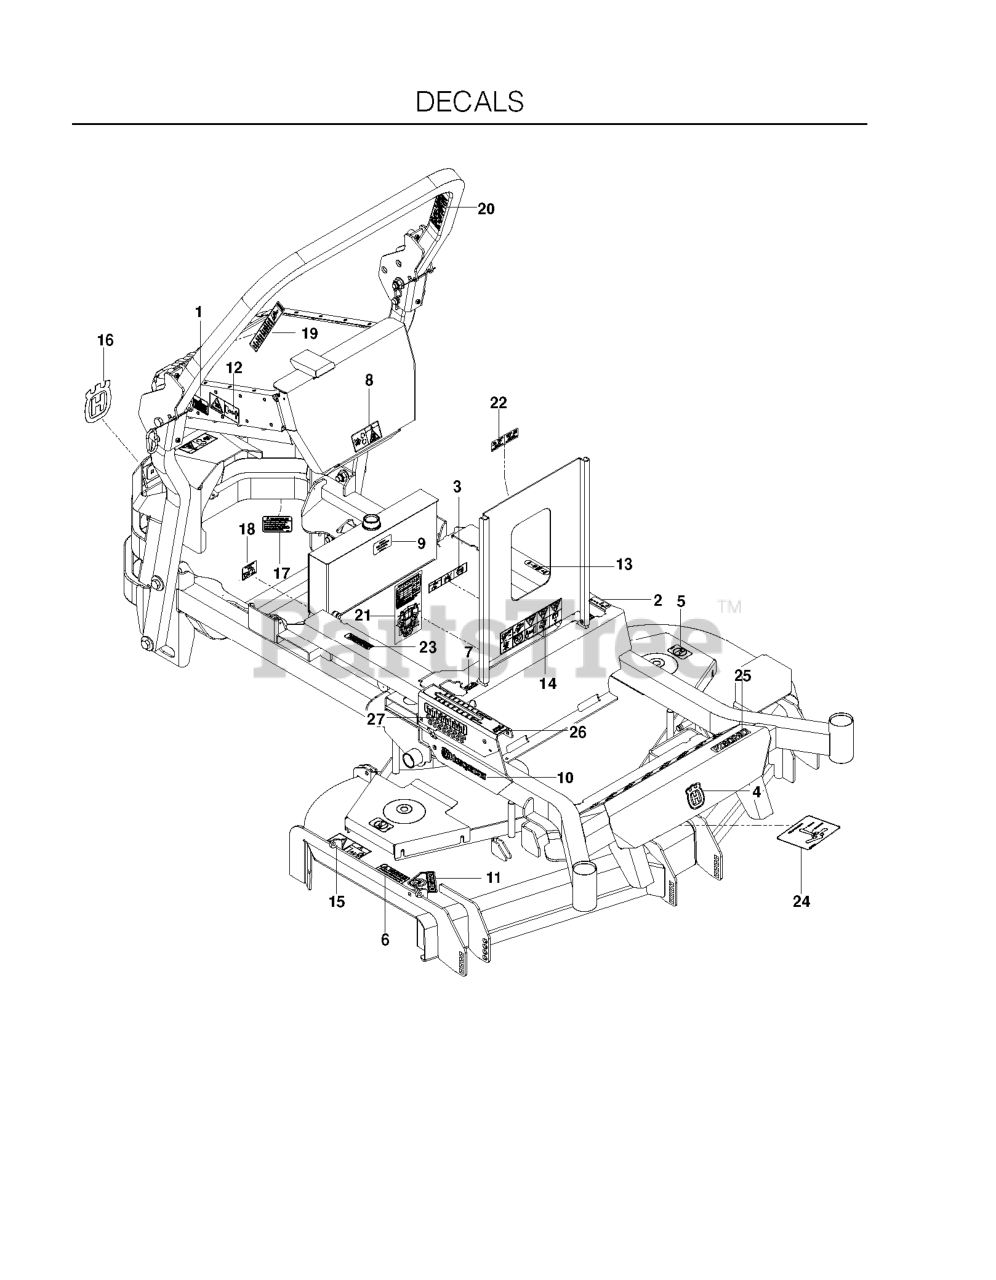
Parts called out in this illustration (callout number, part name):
1	DECAL, DEBRIS SCREEN
2	DECAL, MOTION CONTROL
3	EURO DECAL-BATTERY WARNIN6
4	DECAL, CROWN H 70MM
5	DECAL, NO STEP
6	DECAL, CAUTION
7	DECAL, F.S.T.
8	DECAL, BELT DRIVE
9	DECAL, OIL TANK
10	DECAL.HOOD.LOGO.ORANGE.HUSQVAR
11	DECAL, CPSC
12	DECAL, HOT
13	DECAL, PARK BRAKE
14	DECAL, WARNING
15	DECAL, EURO SEVERING
16	DECAL, CROWN H, 110MM
17	DECAL, PROP. 65
18	DECAL, HYDRO BELT
19	DECAL, ROPS, WARNING
20	DECAL, ROPS, DIESEL
21	DECAL, SERVICE, DIESEL
22	DECAL, FUSE, DIESEL
23	DECAL, WARNING SPARK ARRESTOR
24	DECAL, BELT ROUTING
25	DECAL, PZ6029D
26	DECAL, HEIGHT
27	DECAL, HEIGHT
